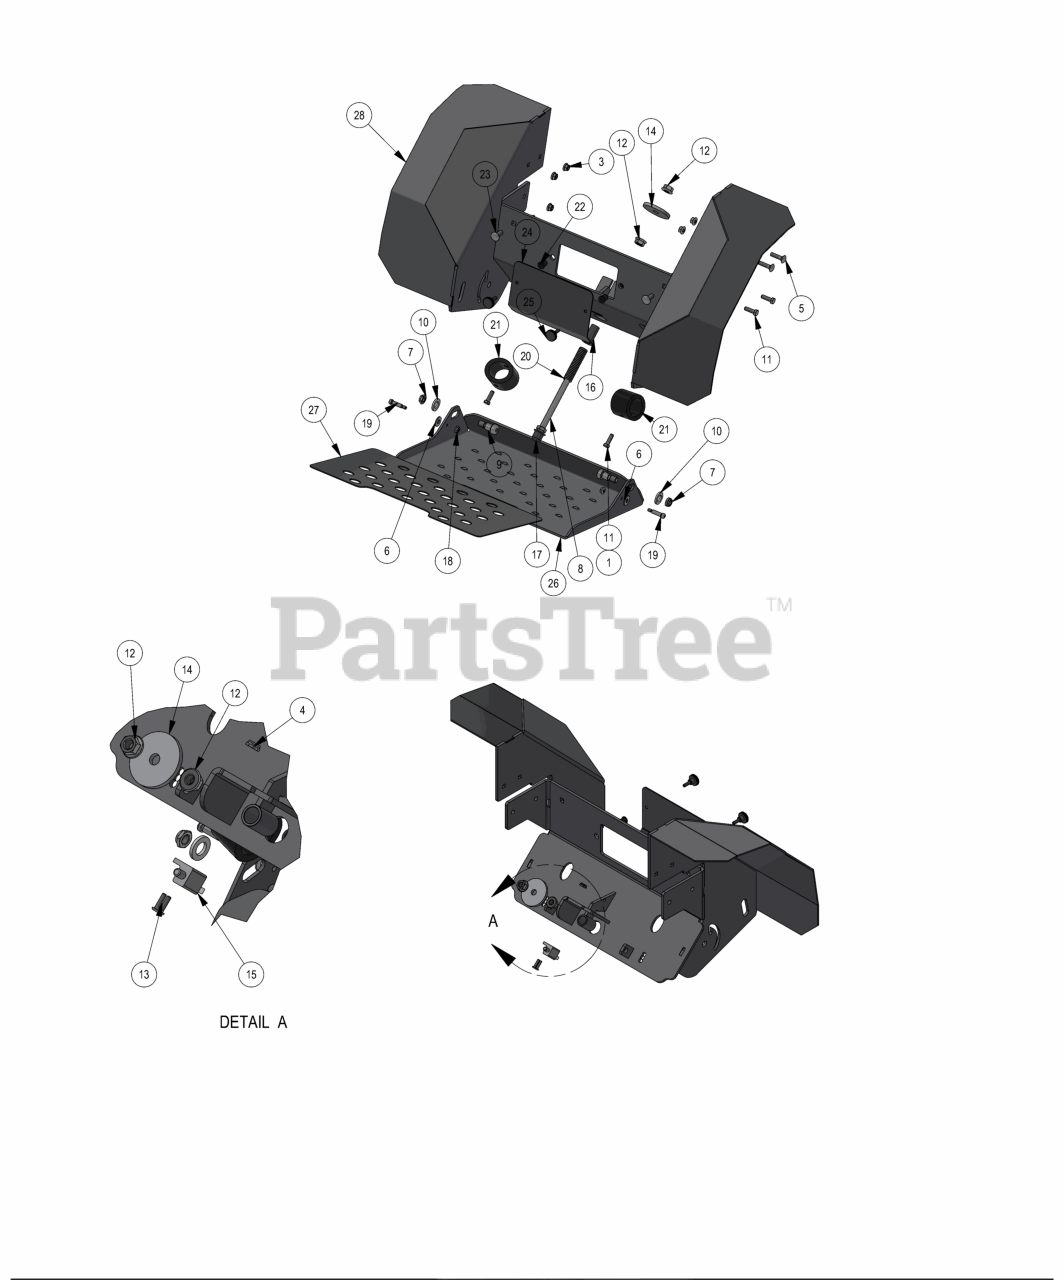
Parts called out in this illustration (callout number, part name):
1	5/16-18 HEX SERRATED FLANGE NUT HARD/ZINC
2	3/8 Nylock Flange Nut
3	5/16-18 NYLON INSERT FLANGE LOCKNUT ZINC
4	10-24 NYLON INSERT LOCKNUT ZINC
5	5/16-18 X 1-1/4 CARRIAGE BOLT ZINC
6	5/16 USS FLAT WASHER (7/8 OD) ZINC
7	1/2-13 Nylon Insert Nut
8	1/2-13 X 6 HEX CAP SCREW (GR.5) ZINC
9	5/8 X 5/8 SOCKET SHOULDER BOLT ZINC YELLOW
10	.635 ID X 1.120 OD X .140 THICK FLAT WASHER NYLON
11	5/16-18 X 1 HEX CAP SCREW (GR.5) ZINC
12	1/2-13 HEX SERRATED FLANGE NUT HARD/ZINC
13	10-24 X 3/4 BUTTON SOCKET CAP SCREW 18-8 STAINLESS STEEL
14	MZ Deck Idler Spacer
15	safety Switch
16	.504 ID X .740 OD X 1.625 LGTH SLEEVE WASHER NYLON
17	Hex Nut Cap
18	1/4-20 HEX SERRATED FLANGE NUT HARD/ZINC
19	Steel Shoulder Screw 1/4"-20 x 7/8" Diameter 5/16"
20	Rider Presence Spring 9657K145
21	2019 Revolt Platform Dampener
22	3326 Wellnut (1/4-20 x 5/18")
23	3/8-16 X 1 CARRIAGE BOLT (GR.5) ZINC
24	2019 Stand On Access Panel Plate Black Part
25	1/4"-20 x 3/4" Knurled Thumb Screw
26	2020 36" Stand-On Platform Plate-RAW
27	Grip Tape for 026-0158-00
28	2023 SD 34 Platform Support
